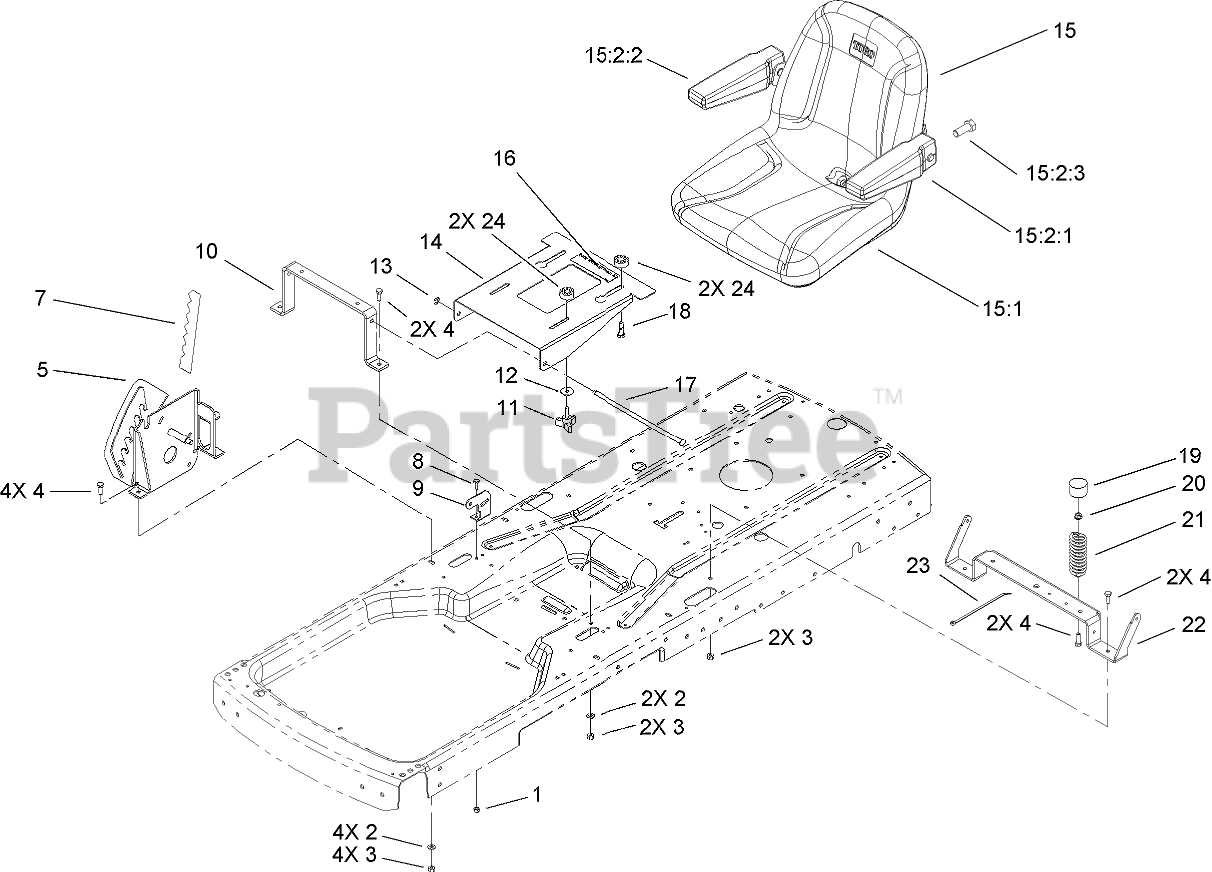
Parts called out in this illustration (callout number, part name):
1	NUT-LOCK, NI
2	WASHER-PLAIN
3	NUT-LOCK, NI
4	SCREW-HH
5	RH PLATE ASM
7	DECAL-HOC
8	SCREW-HH
9	BRACKET-BELLCRANK
10	BRACE-SEAT, FRONT
12	WASHER-PIVOT
13	E-RING
14	BRACKET-SEAT
15	SEAT (WITH ARM RESTS)
15:1	SEAT
15:2:1	LH ARMREST KIT
15:2:2	RH ARMREST KIT
15:2:3	SCREW-HSBH
16	DECAL-SERVICE, CE
17	PIN-PIVOT
18	SCREW-SHOULDER
19	CAP-PROTECTOR
20	NUT-HF
21	SPRING-COMPRESSION
22	BRACE-SEAT, REAR
23	TIE-CABLE
24	SPACER-NYLON
